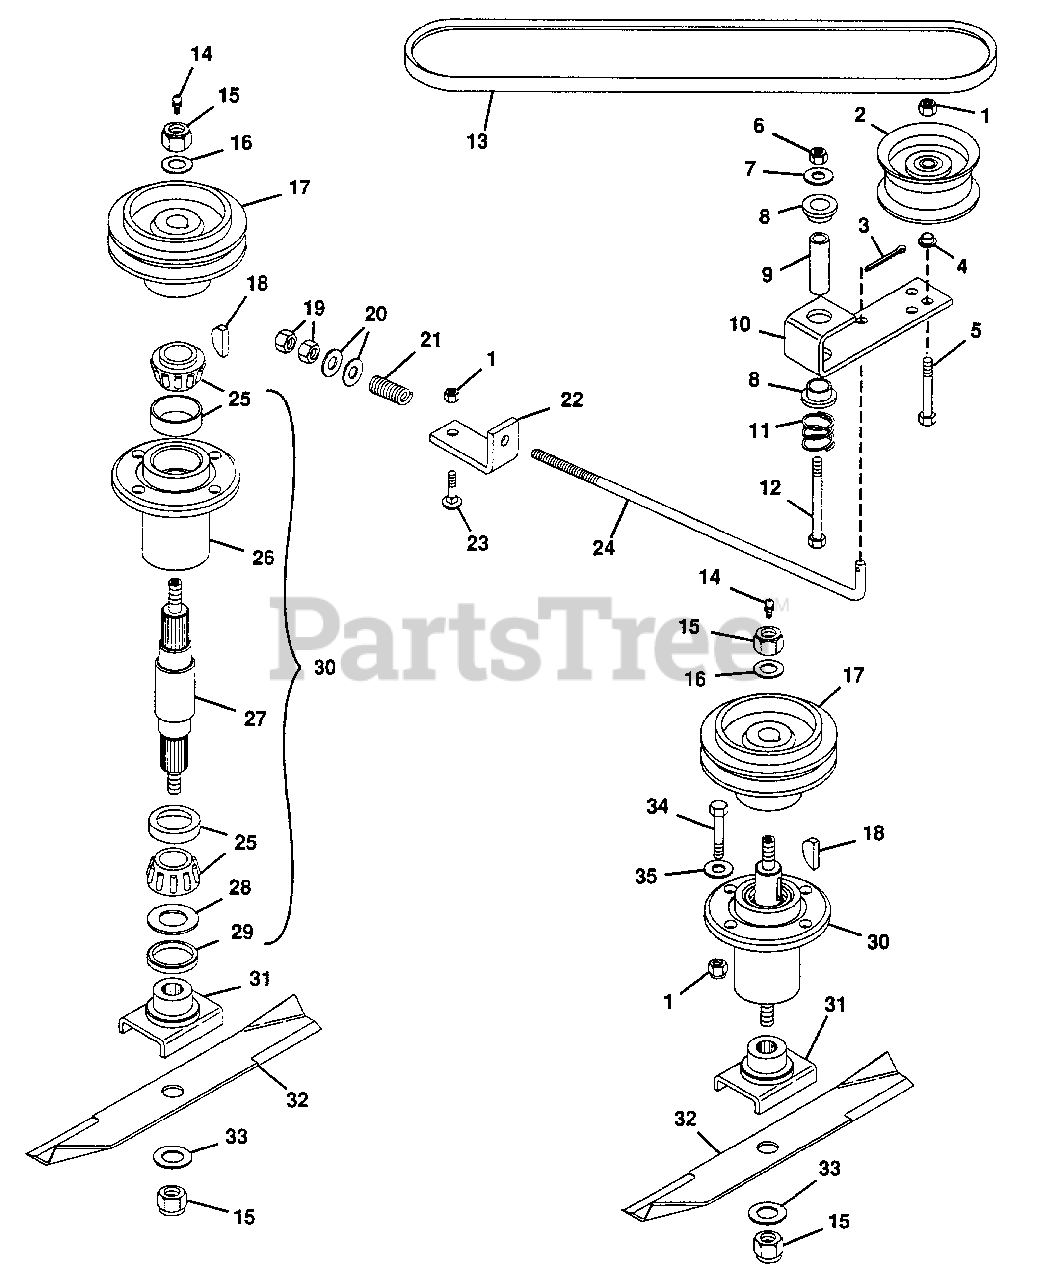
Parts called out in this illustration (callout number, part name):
1	Nut, Lock 3/8-16
2	Pulley, Idler
3	Pin, Cotter .09x.75
4	Bushing, Flange Bronze
5	Bolt, Hex 3/8-16x2.25
6	Nut, Lock 1/2-13
7	Washer, Flat .531x1.250x.100
8	Bushing, Flange Nylon
9	Bushing, St. .560x.750x2.44 Stl.
10	Arm, Idler Pivot
11	Spring, Comp. 1x.80x36 Lb/N
12	Bolt, Hex 1/2-13x3.25
13	Belt, Pro-40 Mower
14	Fitting, Lube 1/8
15	Nut, Lock 5/8-11
16	Washer, Flat .687x1.312x.122
17	Sheave
18	Key, Woodruff 1/4x1 Hard #15
19	Nut, Hex 3/8-24
20	Washer, Flat .406x.812x.065
21	Spring, Comp. 1x.78x338 Lb/N
22	Bracket, Belt Tensioner
23	Bolt, 3/8-16x1.00 Rd Hd Sq Nk
24	Rod, Idler
25	Assembly, Bearing
26	Housing, Bearing
27	Shaft, Spindle
28	Washer, Flat .975x1.970x.030
29	Seal, Steel
30	Assembly, Spindle
31	Weldment, Blade Cradle
32	Blade
33	Washer, Flat .656x1.312x.095
34	Bolt, Hex 3/8-16x1.25
35	Washer, Flat .438x1.000x.083
